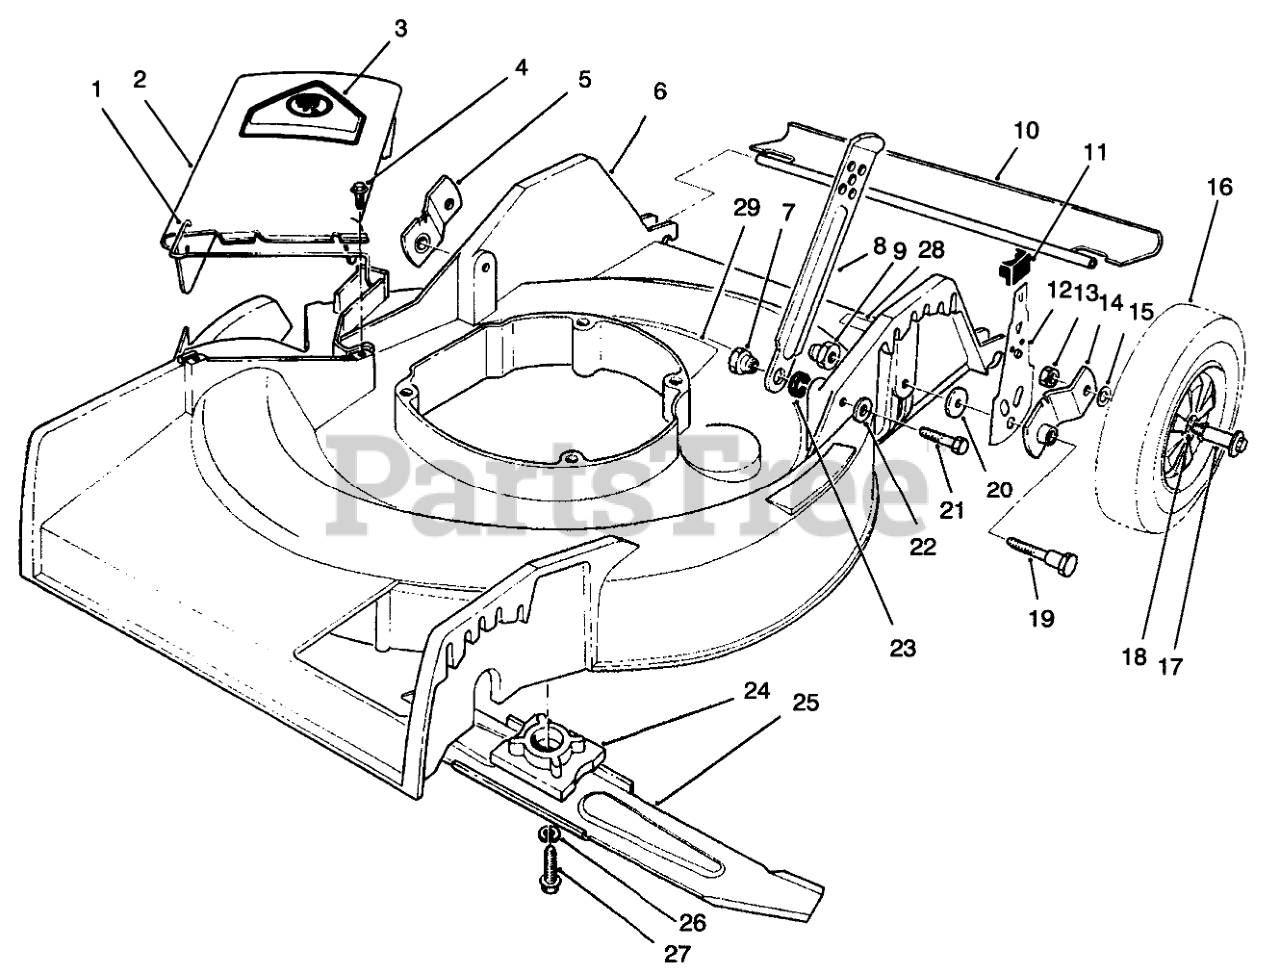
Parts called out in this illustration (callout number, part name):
1	SPRING HINGE
2	Deflector Assembly (Incl. Ref. #1 & 3)
3	DECAL-DANGER
4	SCREW-HWH
5	Pivot Arm
6	Housing-21" (Incl. Ref. #28 & 29)
7	HANDLE PIVOT NUT
8	Latch-Handle
9	HANDLE PIVOT NUT
10	SHIELD - TRAILING
11	KNOB-ARM
12	REAR SPRING ARM ASM
13	NUT-LOCK
14	Pivot Arm
15	WASHER
16	Wheel & Tire Assembly (Incl. Ref. #18)
17	WHEEL BOLT
18	BUSHING
19	5/16-18 PIVOT SCREW
20	PIVOT WASHER
21	SCREW-HH
22	WASHER-LOCK
23	SPACER
24	BLADE RETAINER
25	Blade
26	WASHER-LOCK
27	SCREW-HH
28	DECAL-WARNING
29	DECAL-INSTRUCTION, SAFETY
